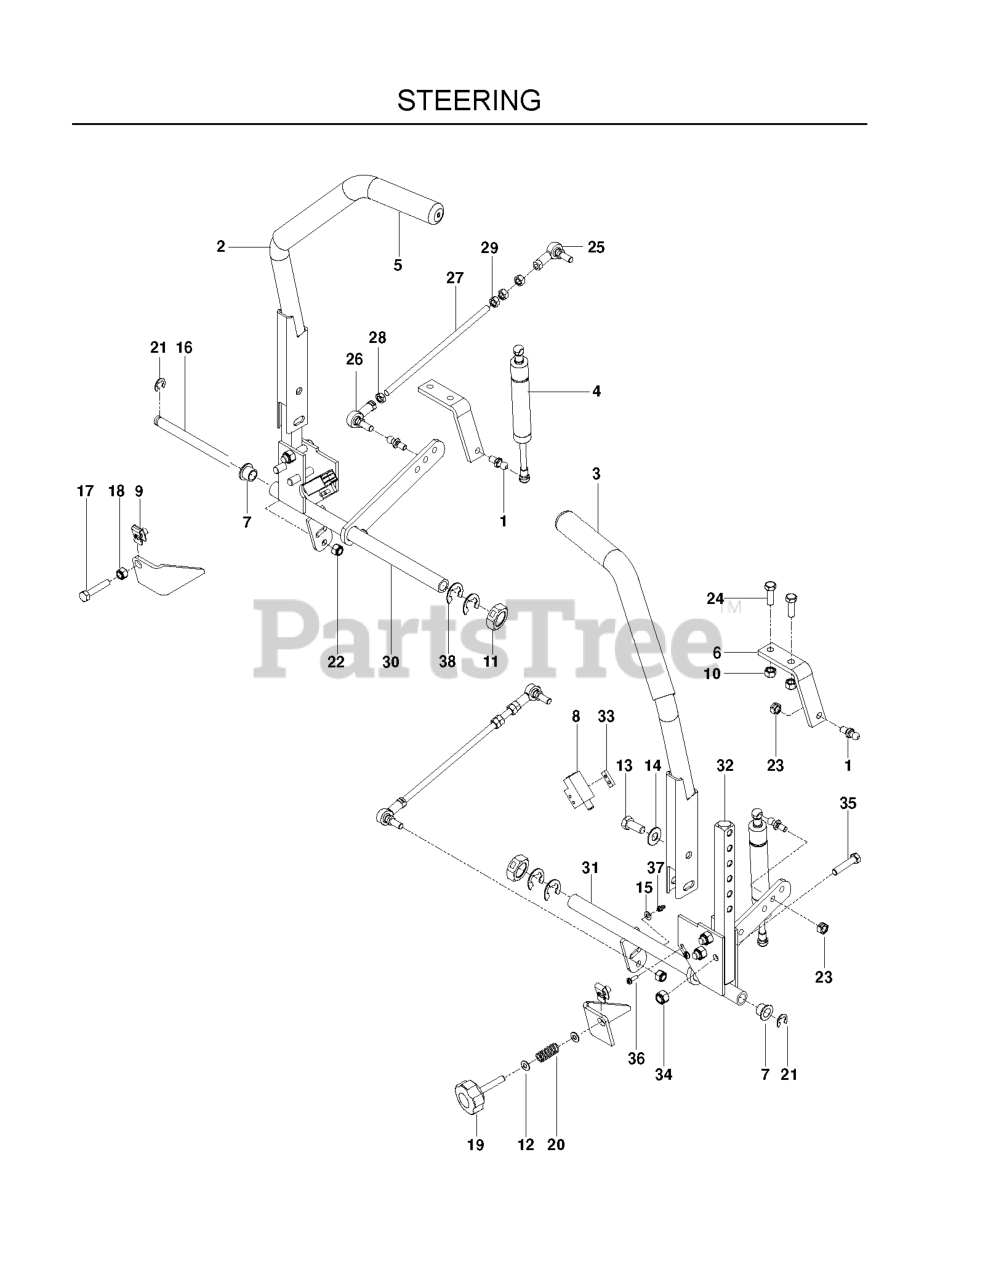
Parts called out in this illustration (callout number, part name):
1	STUD.BALL.10MM
2	ASSEMBLY, DRIVE LEVER RT
3	ASSEMBLY, DRIVE LEVER LT
4	DAMPENER W/EXT SEAL
5	GRIP - DRIVE LEVER 12"
6	DAMPENER BRACKET
8	SWITCH, INTERLOCK
9	U-CLIP 5/16-18 NUT RETAINER
10	NUT 5/16 NYLOC
11	NUT 3/4 X 16 HEX CTR
12	WASHER 5/16 FLAT
13	HCS 3/8-16X1.GRD.5.ZD
14	WASHER, 3/8 DISC SPRING SPEC
16	CONTROL SHAFT
17	HCS 5/16-18X1-3/4 TPBLT
18	NUT 5/16C HEX
19	ADJUSTMENT KNOB
20	COMPRESSION SPRING
21	E-RING 1/2 (2 2)
22	NUT 5/16F NYLOC
23	NUT 5/16C CENTERLOCK
24	HCS 5/16C X 1
25	SPHERICAL ROD END, RH
26	SPHERICAL ROD END, LH
27	PUMP CONTROL LINK
28	NUT 5/16F LEFTHAND
30	CONTROL ASM - ADJ, RT
31	CONTROL ASM - ADJ, LT
32	CONTROL ARM
33	TAPPED PLATE
34	NUT 3/8-16 NYLOC
35	HCS 3/8-16 X 1 3/4 GR5
36	SCREW #10-24 X 5/8
37	ZERK
38	E-RING 5/8
